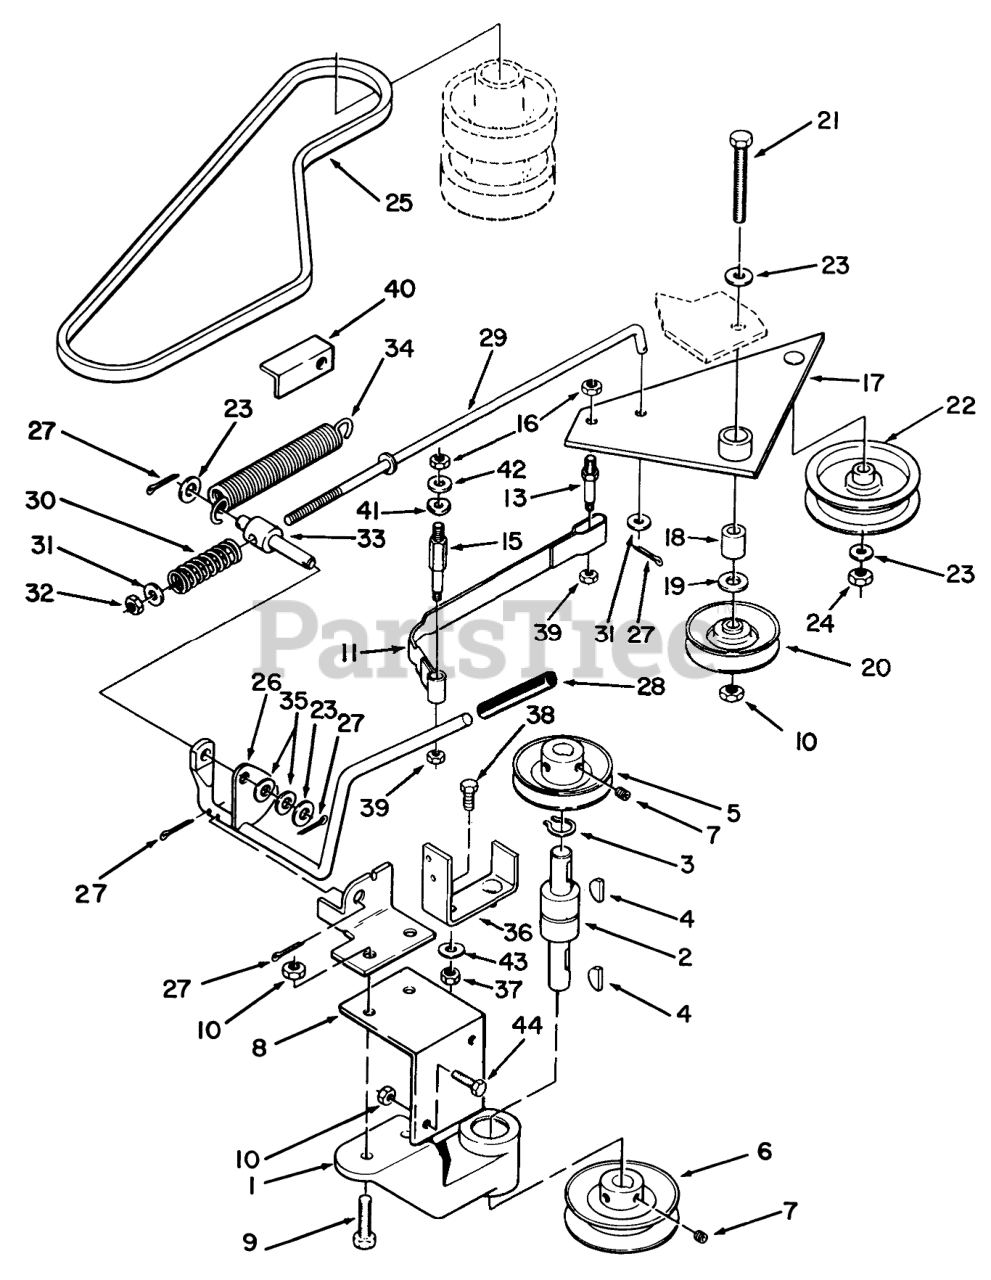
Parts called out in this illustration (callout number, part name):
1	HOUSING DRIVE BRG R
2	BEARING-INT SHAFT
3	RING-SNAP
4	KEY-WOODRUFF
5	PULLEY CAST IRON
6	PULLEY
7	SCREW-SET, HSH
8	JACKSHAFT-BRACKET R
9	SCREW-HH
10	NUT-LOCK, NI
11	BAND BRAKE
13	STUD-SHOULDER
15	STUD-SHOULDER LONG
16	NUT-HEX
17	BLADE LEVER ASSY R
18	SPACER
19	Washer
20	IDLER PULLEY
21	SCREW-HH
22	Idler Pulley
23	WASHER-FLAT
24	NUT-HEX, JAM
25	BELT-V
26	ASSY HANDLE PTO CLUT
27	PIN-COTTER
28	GRIP
29	ASSY ROD PTO
30	SPRING COMPRESSION
31	WASHER-PLAIN
32	NUT-LOCK, NI
33	TRUNNION
34	SPRING R
36	ASS'Y-BRACKET (L. R
37	NUT-LOCK, NI
38	SCREW-HH
39	NUT-HEX, SIDE DEFORM
40	PTO INDICATOR BRC R
41	WASHER
42	WASHER-PLAIN
43	WASHER-FLAT
44	SCREW-HH
